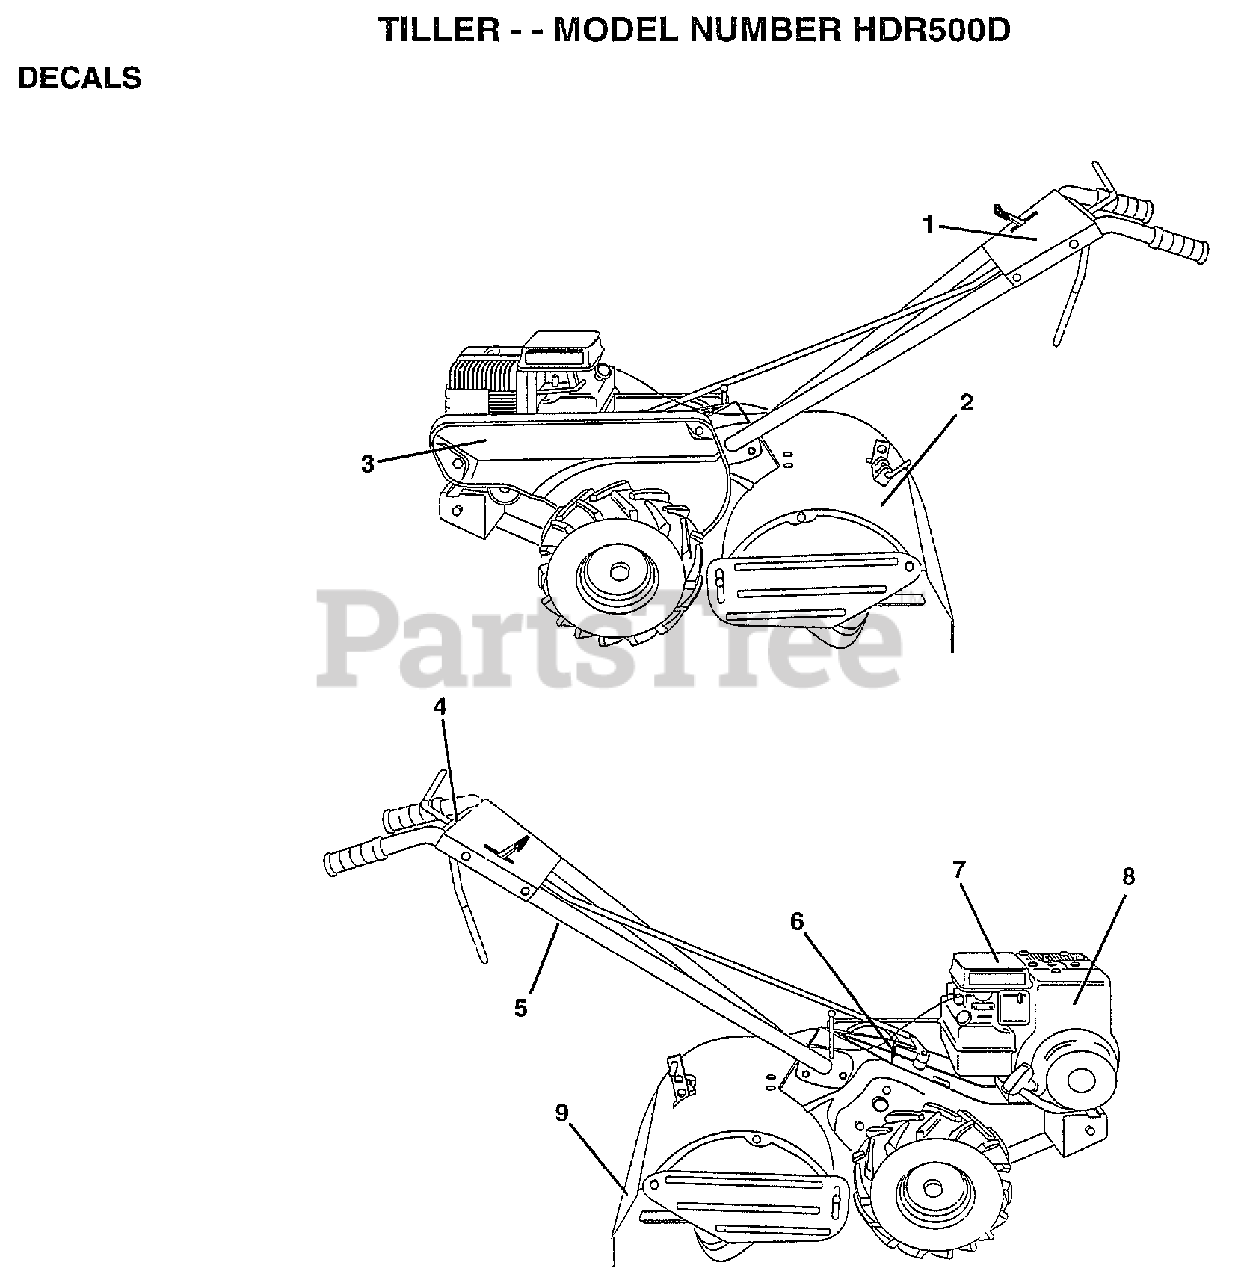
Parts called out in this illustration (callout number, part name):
1	DECAL.CNTRL.PNL.
2	DECAL.SHIELD.TINE
3	DECAL.GRD.BLT.5HP
4	DECAL.CONTROL
5	DECAL.HAND.PLACE
6	DECAL CRT
7	DECAL.CAUTION.E/S
8	DECAL, BRIGGS & STRATTON
9	DECAL.WARN.ROT.TI
